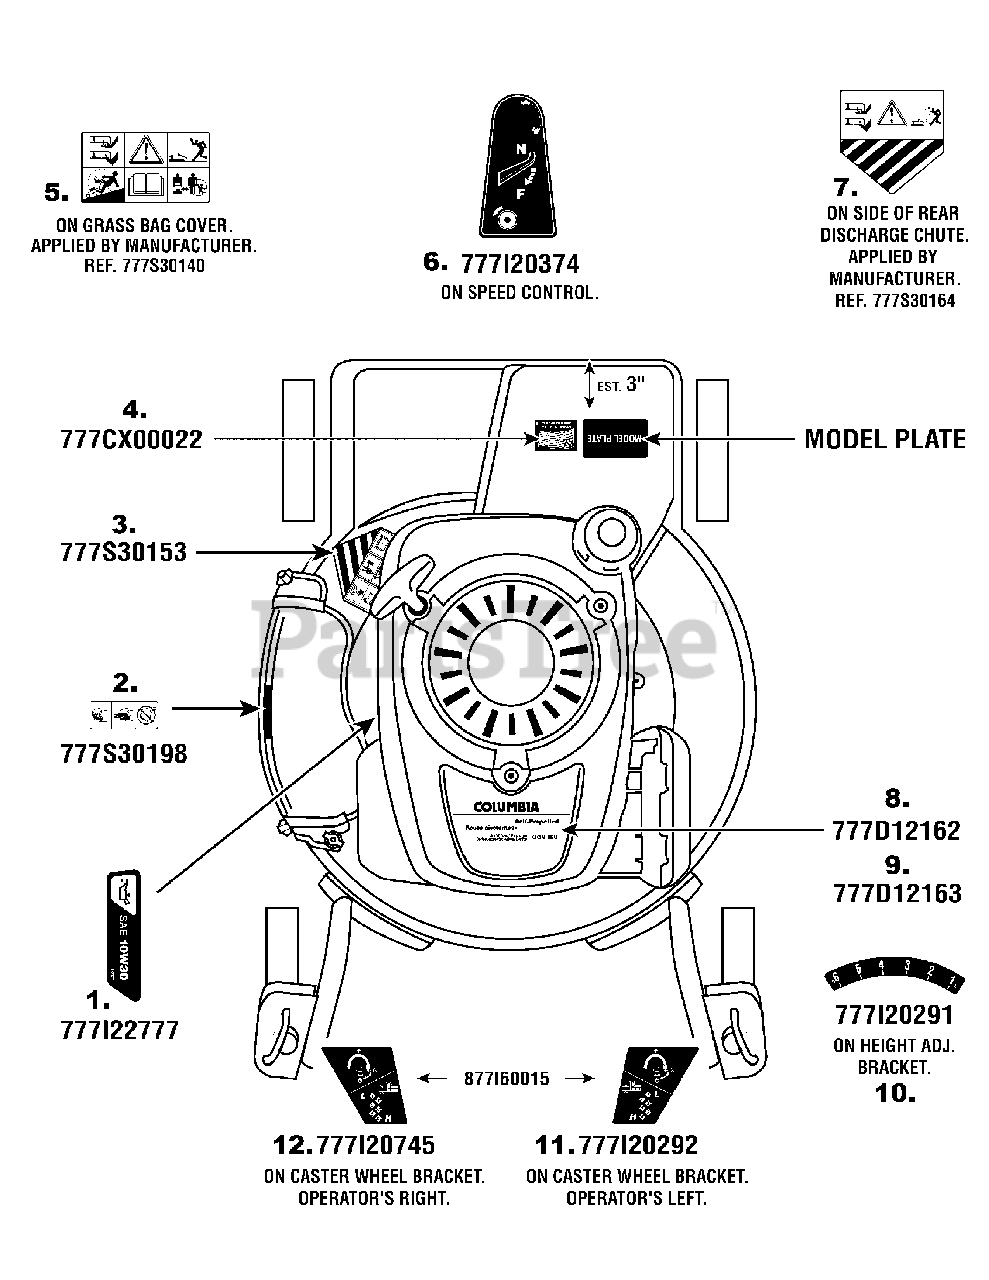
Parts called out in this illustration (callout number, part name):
1	LABEL-10W30 ENG SHROUD
3	LABEL-DANGER CHUTE
4	LBLX: MADE IN USA
6	LABEL SIX SPEED
7	LBL:SAFETY PICT
8	LABEL-ENG SHROUD COLUMBIA 978Q
9	LABEL-ENG SHROUD COLUMBIA 998Q
10	LABEL-HEIGHT ADJUS
11	LABEL-CASTOR LOCK LH
12	LABEL-CASTOR LOCK RH
